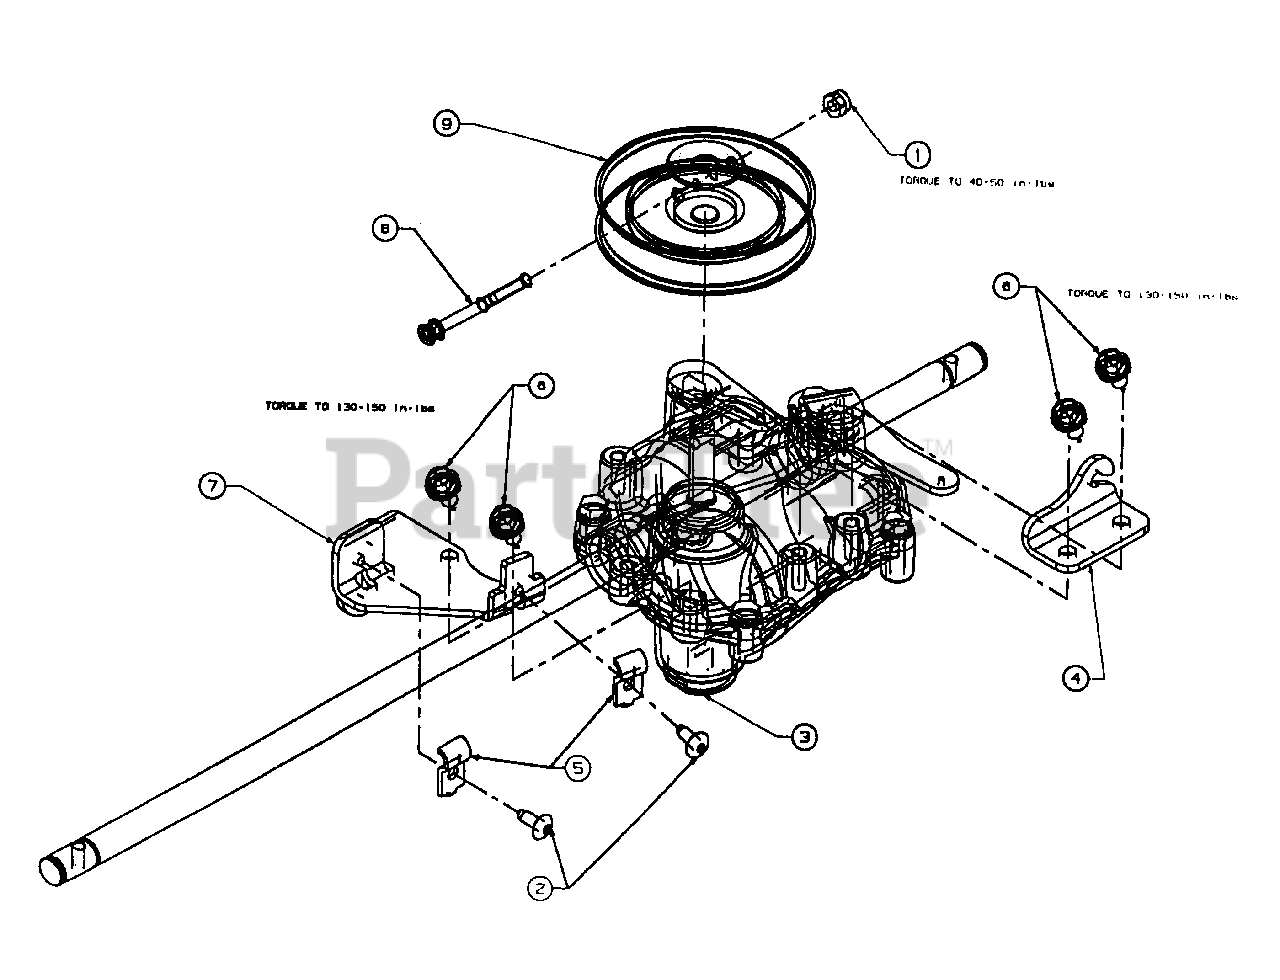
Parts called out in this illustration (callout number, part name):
1	NUT:NYL:LOCK #10-24
2	SCR:8:#10-16:0.500: TRUSTRX1
3	TRANS ASM: 3-SPEED: WBM
4	BRKT:SPG;TRANS, TUFF TORQ
5	CLAMP:CBL: 3/16
6	SCR:TT:1/4-20: .500:HX INDWSH
7	BRKT:CLUTCH:TRANS, TUFF TORQ
8	SCR:SOC:10-24 X 1.25
9	PULLEY: TRANS:3/8 V X 3.50 OD
